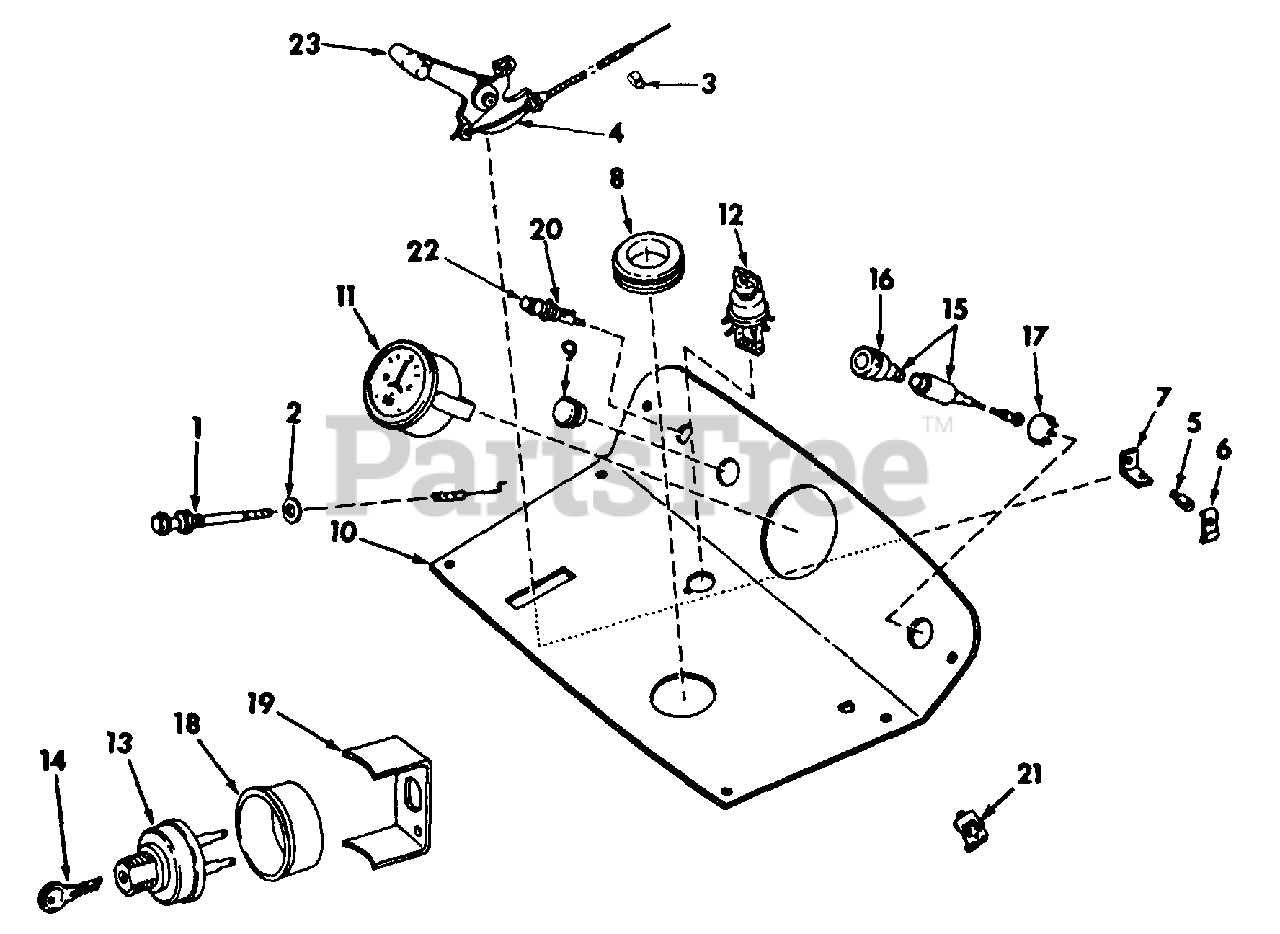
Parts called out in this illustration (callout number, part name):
1	CABLE ASSY, CHOKE LEVER
2	WASHER, .406 X .812 X .051 CRB - BEZEL CHOKE
3	CLIP, THROTTLE CABLE
4	LEVER, THROTTLE CABLE -LESS KNOB
5	PIN, GOVERNOR CONTROL SWIVEL
6	CLAMP, THROTTLE CONTROL
7	BRACKET ASSY, THROTTLE CONTROL
8	GROMMET, INSTRUMENT PANEL
9	SOCKET ASSY, TELLITE FOR 27/32 IN PANEL MOUNTING HOLE
10	PANEL ASSY, INSTRUMENT
11	INDICATOR ASSY, CHARGE
12	SWITCH ASSY, LIGHTING
13	SWITCH ASSY, BATTERY IGNITION KEY
14	KEY, IGNITION SWITCH
15	CIGARETTE LIGHTER PARTS ACCESSORY
16	UNIT, POP OUT
17	PLUG, 29/32 BUTTON CIGARETTE LIGHTER OPENING HOLE
18	SOCKET, IGNITION SWITCH
19	RETAINER, IGNITION SWITCH
20	HOUSING ASSY, FUSE
21	CLIP, SPEED
22	KNOB, FUSE HOLDER
23	KNOB, THROTTLE CONTROL CABLE LEVER
